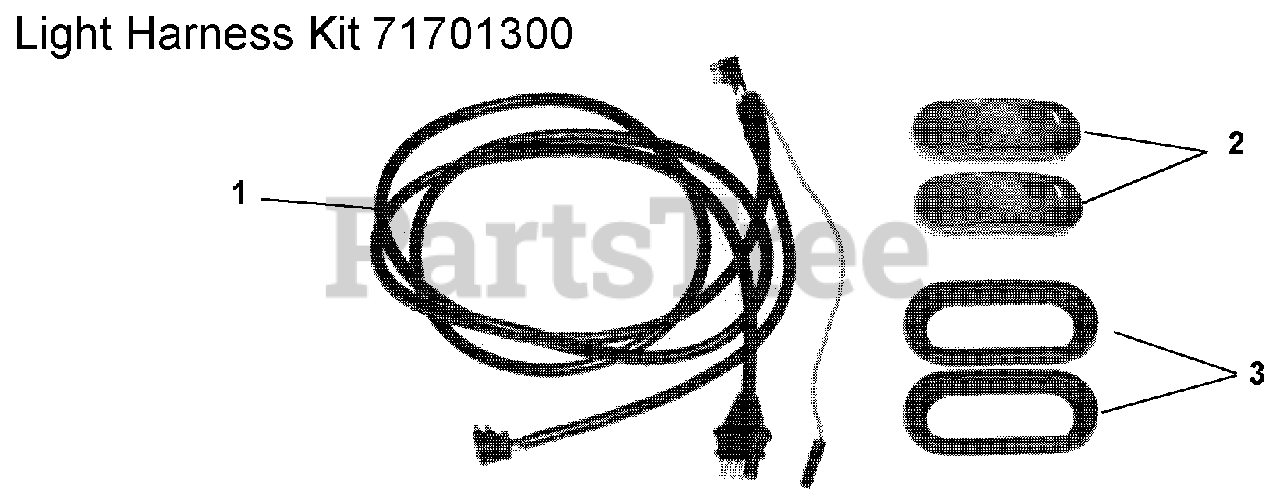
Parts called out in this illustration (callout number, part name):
1	WIRE HRNS,TRAILER LIGHT KIT
2	TAIL LIGHT HOUSING W/ BULB
3	GROMMET, TAIL LIGHT MOUNTING
